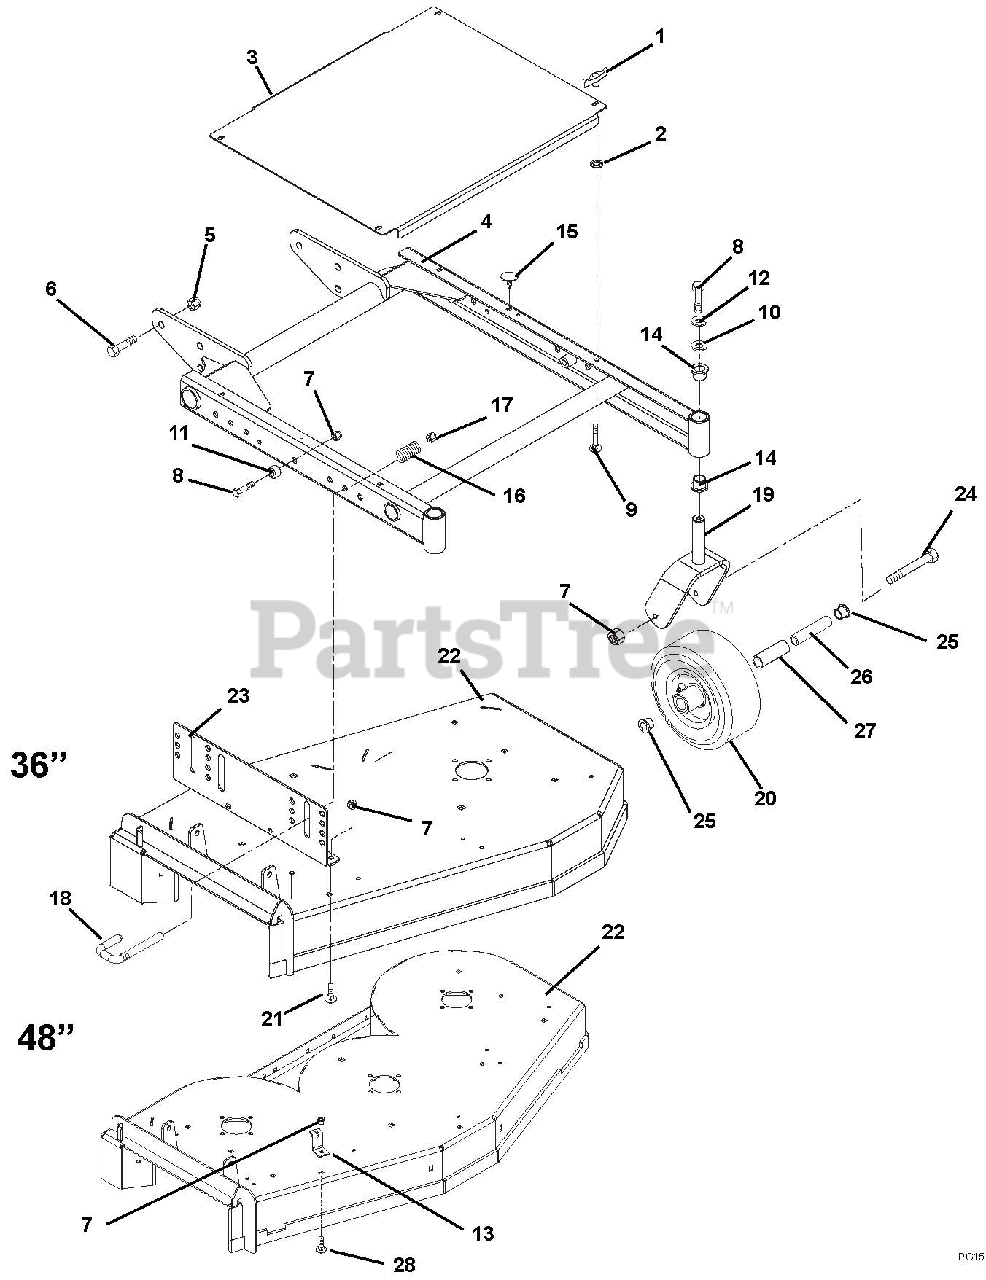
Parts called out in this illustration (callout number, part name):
1	Knob- Wing .312-18
2	Nut-Push .312
3	Cover, Belt Pro Mower
4	Weldment - Mower Frame 36"
4	Weldment - Mower Frame 48"
5	Nut-Locking-Nylon .625-11
6	Bolt-Hex .62-11 x 1.50
7	Nut-Locking-Top-Flange .38-16
8	Bolt-Hex .38-16 x 1.25 Grade 5
9	Bolt-Round Head Square Neck .31-18 x 1.00
10	Washer-Flat-Steel .38 x 1.50 x .125
12	Washer-Locking .38 x .094 Regular
13	Anchor, Spring
14	Bushing-Flange 1.00 x 1.25 x 1.50 x 1.50
15	Bumper Grommet .125 x .25 Dia.
16	Spring-Compression .058 x .65 x 2.13
17	Nut-Locking-Center .50-13
18	Pin- Latch
19	Weldment-Caster Fork
20	Wheel 9 x 3.50
21	Bolt-Round Head Square Neck .38-16 x 1.00 Grade 5
22	Kit, 36" Fixed Mower Deck with Decals
22	Kit, 48" Fixed Mower Deck with Decals
23	Kit-Mower Side Support Bracket-Right Hand and Left Hand
24	Bolt-Hex .38-16 x 5.50
25	Bearing-Retainer
26	Bearing .625 x .380 x 4.08
27	Bearing-Roller
28	Bolt-Round Head Square Neck .38-16 x .75 Grade 5
